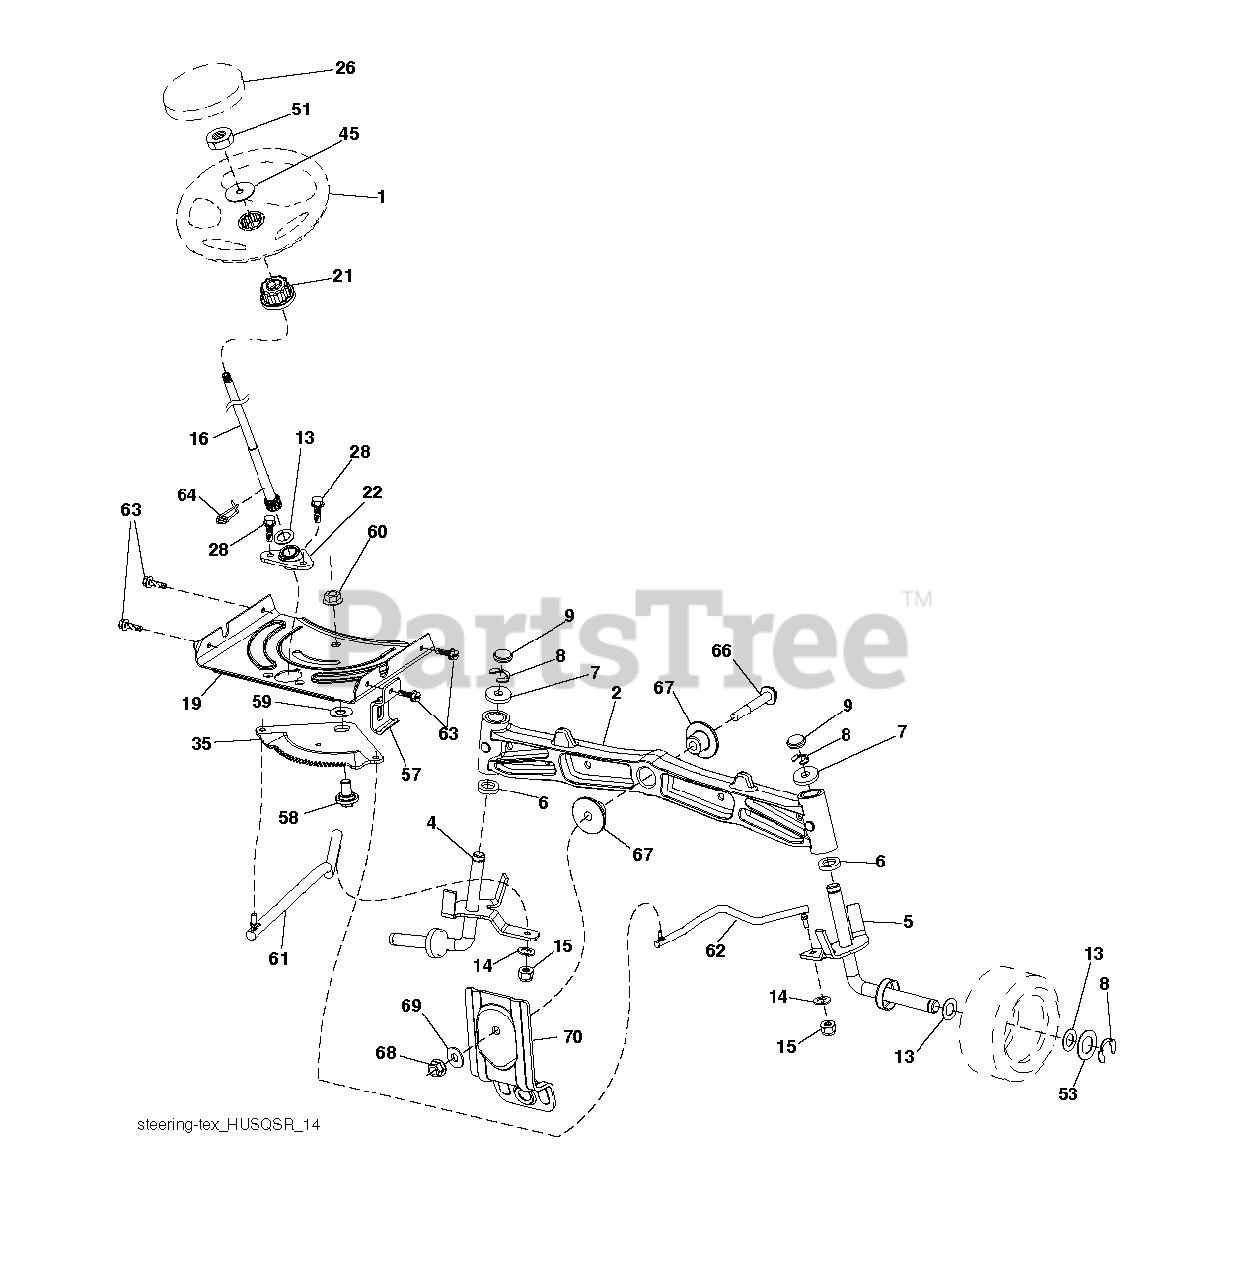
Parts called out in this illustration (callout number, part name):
1	WHEEL.STEER.HUSQ.SR.498.OVMLD
2	AXLE.CAST.IRON
4	SPINDLE.WELDED.LH.15"TEX
5	SPINDLE.WELDED.RH.15"T
6	THRUST WASHER
9	CAP.SPINDLE.BLACK
14	WASHER, LOCK 3/8
15	NUT CROWNLOCK 3/8-24
16	SHAFT.STEER.STEALTH.DD
19	PLATE.STEER.DDL.NLT/NG
21	ADAPTER, WHEEL STNG..
22	STEERING.SUPT.LOWER.
26	INSERT.CAP.WHL.STRG.HUSQ.PREM
28	SCREW, 3/8-16X3/4
35	GEAR.SECTOR.PLATE.DDL.
45	WASHER 9/16"ID, 2 3/8"OD
51	NUT.HEX.1/2-20
53	WASHER.HARDENED
57	BRKT.UPSTOP.GT/LT.TEX
58	BOLT.SHOULDER.SECTOR.P
59	WASHER.THURST.SECTOR.S
60	NUT FLANGE LOCK 5/8-11
61	DRAGLINK.LH.BALLSTUD.D
62	DRAGLINK.RH.BALLSTUD.D
63	SCREW
64	RETAINER.CLIP.SPRING.S
66	BOLT HEX FGHD 7/16-14 X 3 SERR
67	BUSHING.PM.FRONT AXLE
68	NUT.LOCK.FLANGE.7/16
69	WASHER.1.5X.505X.118
70	BRKT.DECK.SUSPENSION.F
